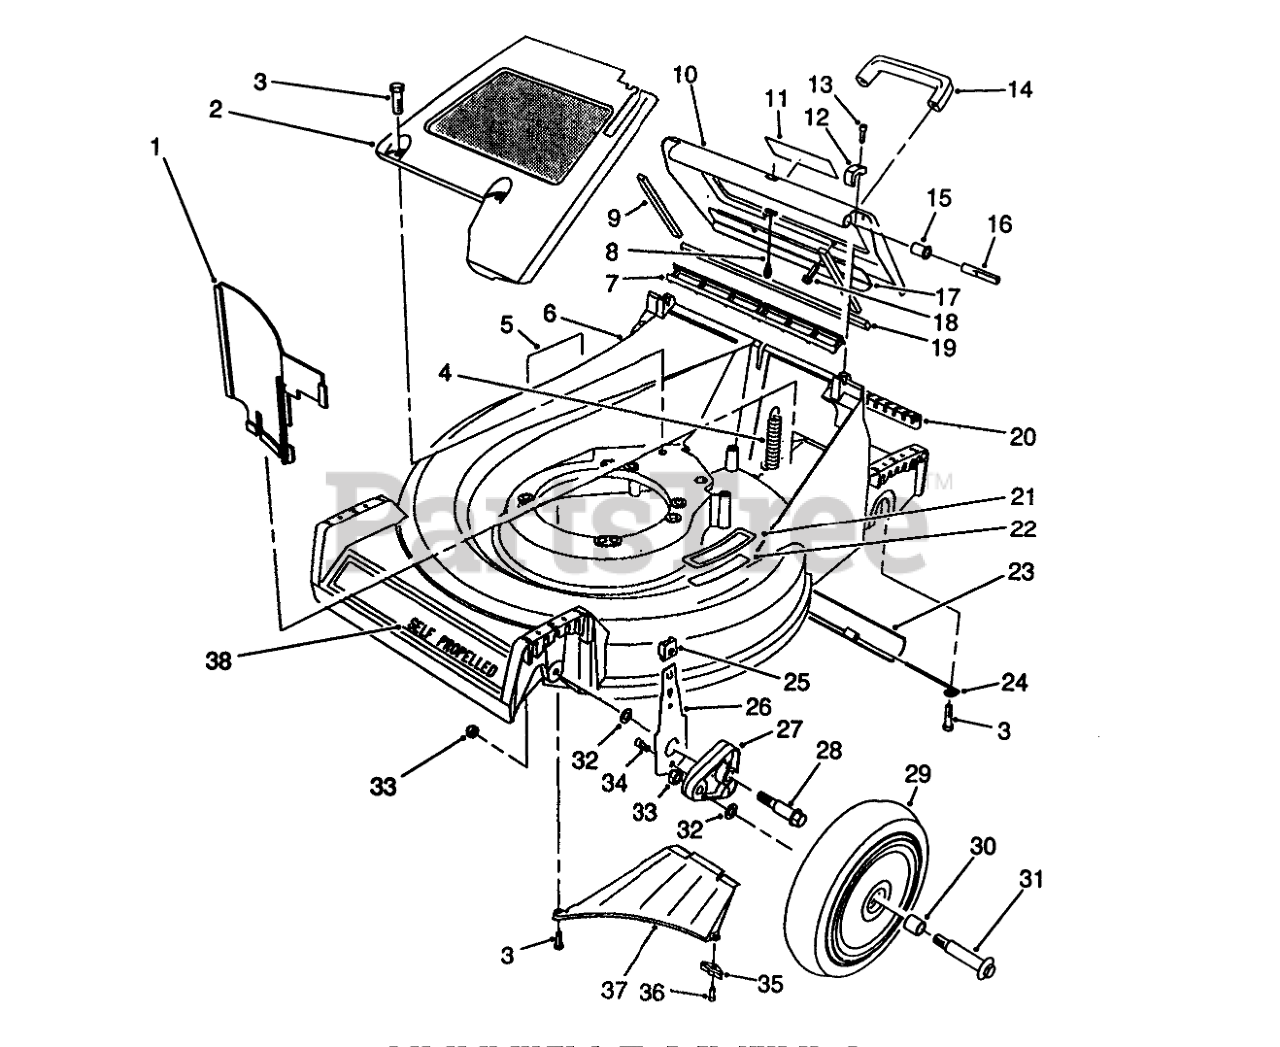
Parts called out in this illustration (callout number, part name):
1	PANEL-VERTICAL
2	PaneI-Screen
3	SCREW-HWHTF
4	EXTENSION-SPRING
5	DECAL-DANGER
6	21" Housing Assembly (Incl. Ref. #5, 21-22)
7	DOOR SEAL
8	DOOR CABLE
9	DOOR SIDE SEAL
10	Door-Discharge (Incl. Ref. #9, 11, 17 & 19)
11	DECAL - WARNING
12	HINGE CLAMP
13	SCREW-HSH
14	HANDLE-DOOR
15	DOOR BUSHING
16	HINGE PIN
17	DOOR - BRACE
18	SCREW-HWH
19	DOOR END SEAL
20	ACCESS COVER
21	STEP PAD
22	STEP PAD DECAL
23	TRAILING SHIELD
24	LH SHIELD HANGER
25	KNOB-ARM
26	FRONT SPRING ARM ASM
27	ARM-PIVOT, FRONT
28	BOLT-SHOULDER
29	Wheel & Tire Assembly (Incl. Ref. #30)
30	BUSHING
31	WHEEL BOLT
32	WASHER
33	Nut
34	Screw-Cap Socket Hd.
35	Bracket-Discharge
36	SCREW-HWHTF
37	Ramp Discharge
38	DECAL - DECK
